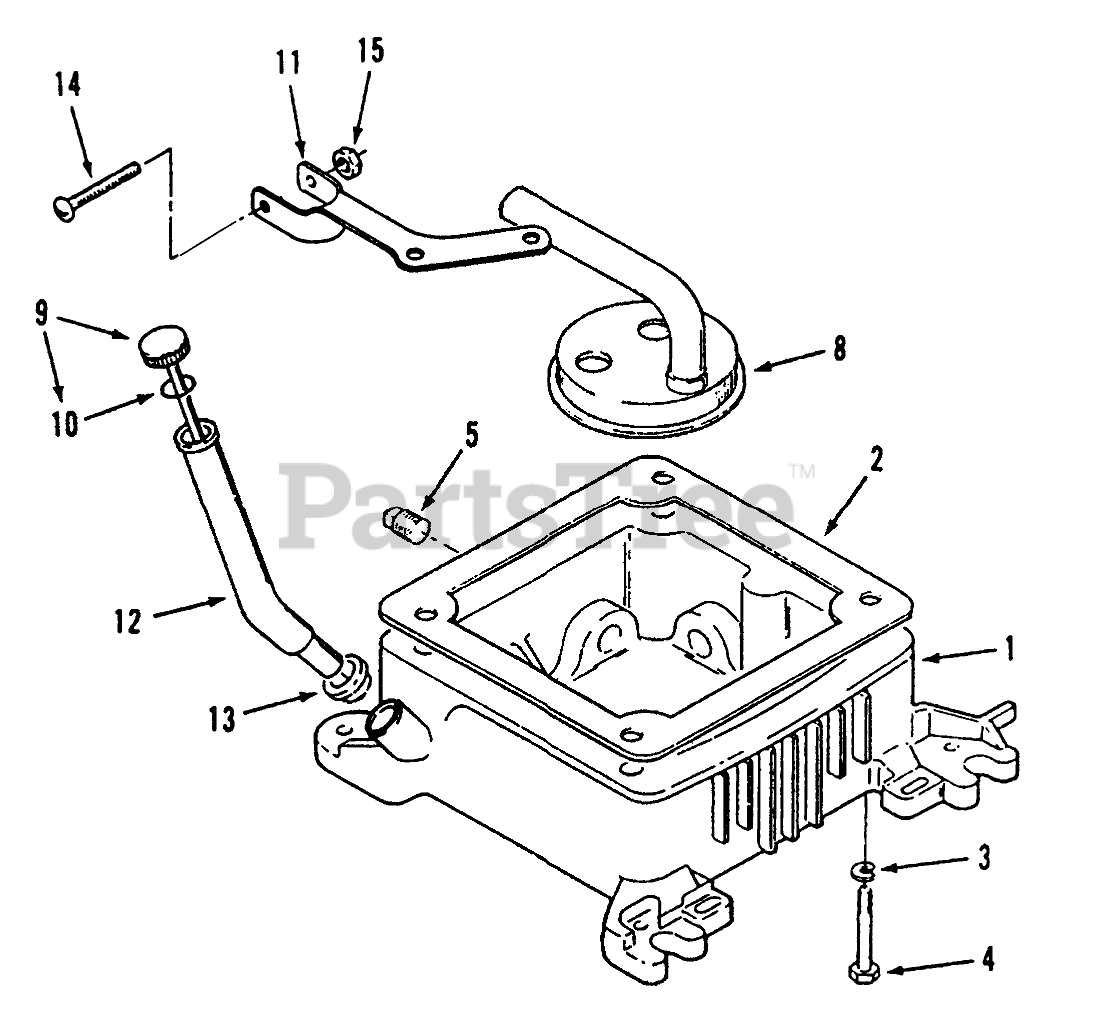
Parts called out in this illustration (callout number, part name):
1	Base-Oil (Incl. All Plugs & Plug Gasket)
2	GASKET
3	WASHER-FLAT
4	HHCS 3/8-16 X 3 3/4
5	PLUG - SQUARE HEAD
8	Cup-Oil Pump Intake
9	Cap-Oil Fill & Indicator (Incl."O"Ring)
10	O-Ring
11	BRACKET-FILL TUBE
12	TUBE-OIL FILL
13	Seal
14	SCREW - PAN HEAD
15	NUT - SPEED
